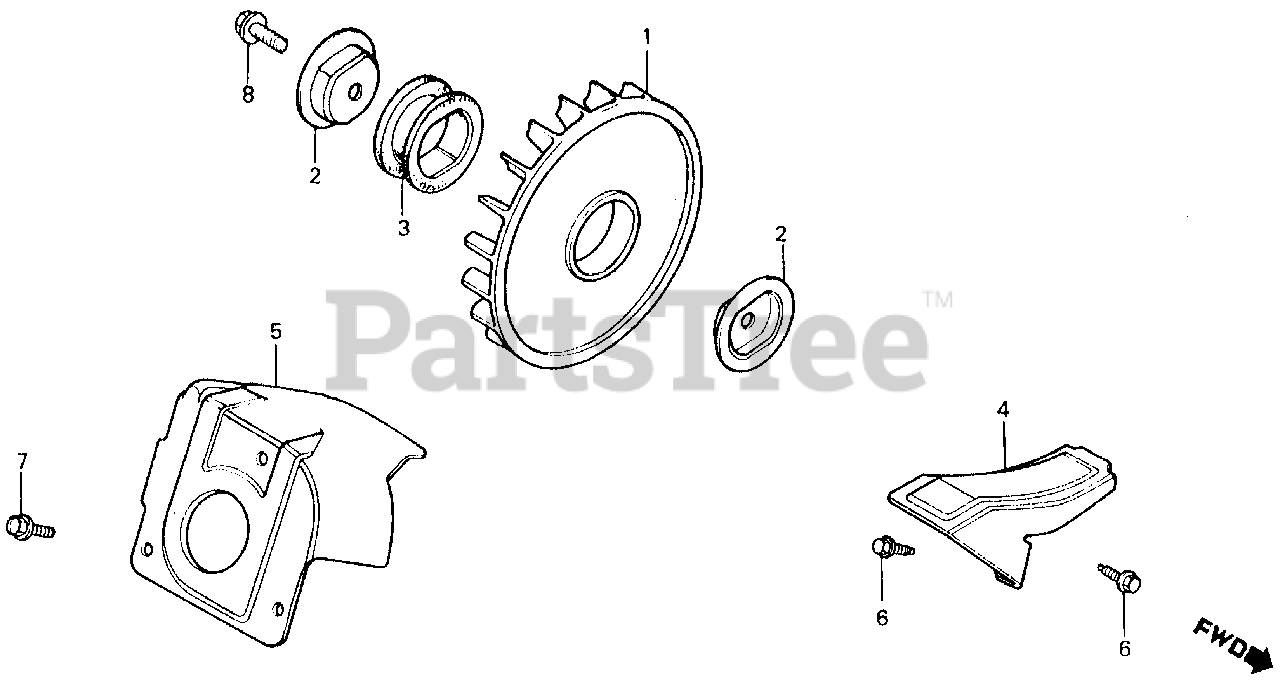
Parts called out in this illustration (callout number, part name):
1	FAN, COOLING (NOT AVAILABLE)
2	PLATE, COOLING FAN SETTING
3	RUBBER, FAN MOUNTING (NOT AVAILABLE)
5	COVER, CYLINDER HEAD
6	BOLT, FLANGE (5X10)
7	BOLT, FLANGE (6X12)
8	BOLT, FLANGE (8X16)
